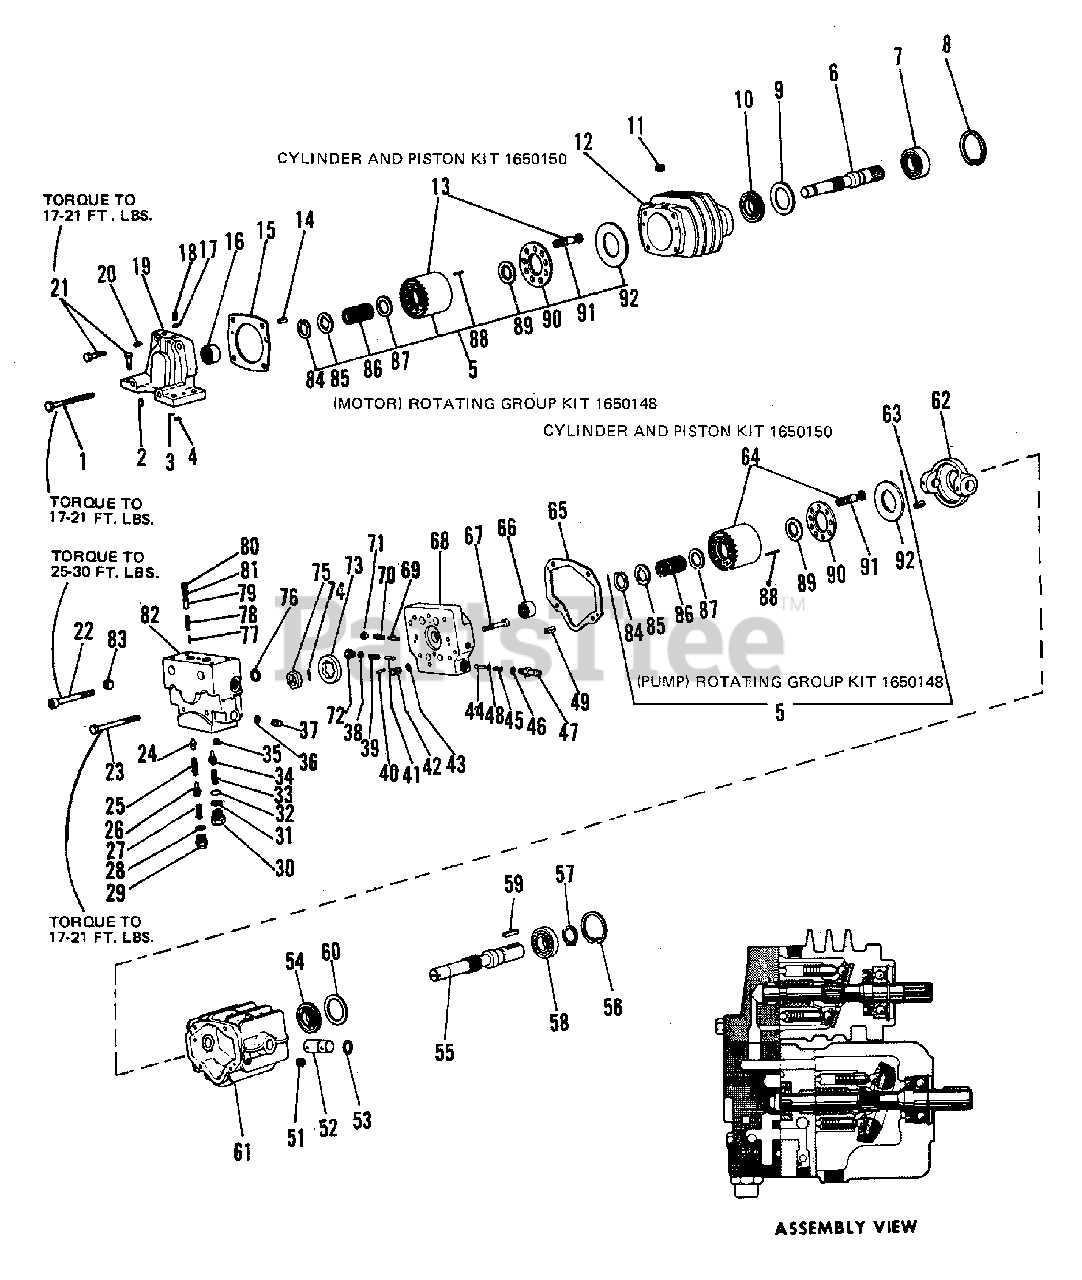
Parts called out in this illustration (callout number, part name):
1	Screw
5	Motor Rotating Group Kit
8	Snap Ring
12	Motor Housing
13	Cylinder Block & Piston Kit
19	Valve Plate (Inludes Bearings 16)
21	Screw
24	Poppet Sub-assembly
26	Pin Sub-assembly
47	Connector
50	Pump Rotating Group Kit
56	Snap Ring
57	Snap Ring
61	Pump Housing
64	Cylinder Block & Piston Kit
68	Valve Plate
73	Outer Rotor
75	Inner Rotor
82	Transfer Block
84	Snap Ring
89	Spherical Washer
90	Shoe Plate
91	Pistons
92	Swash Plate
